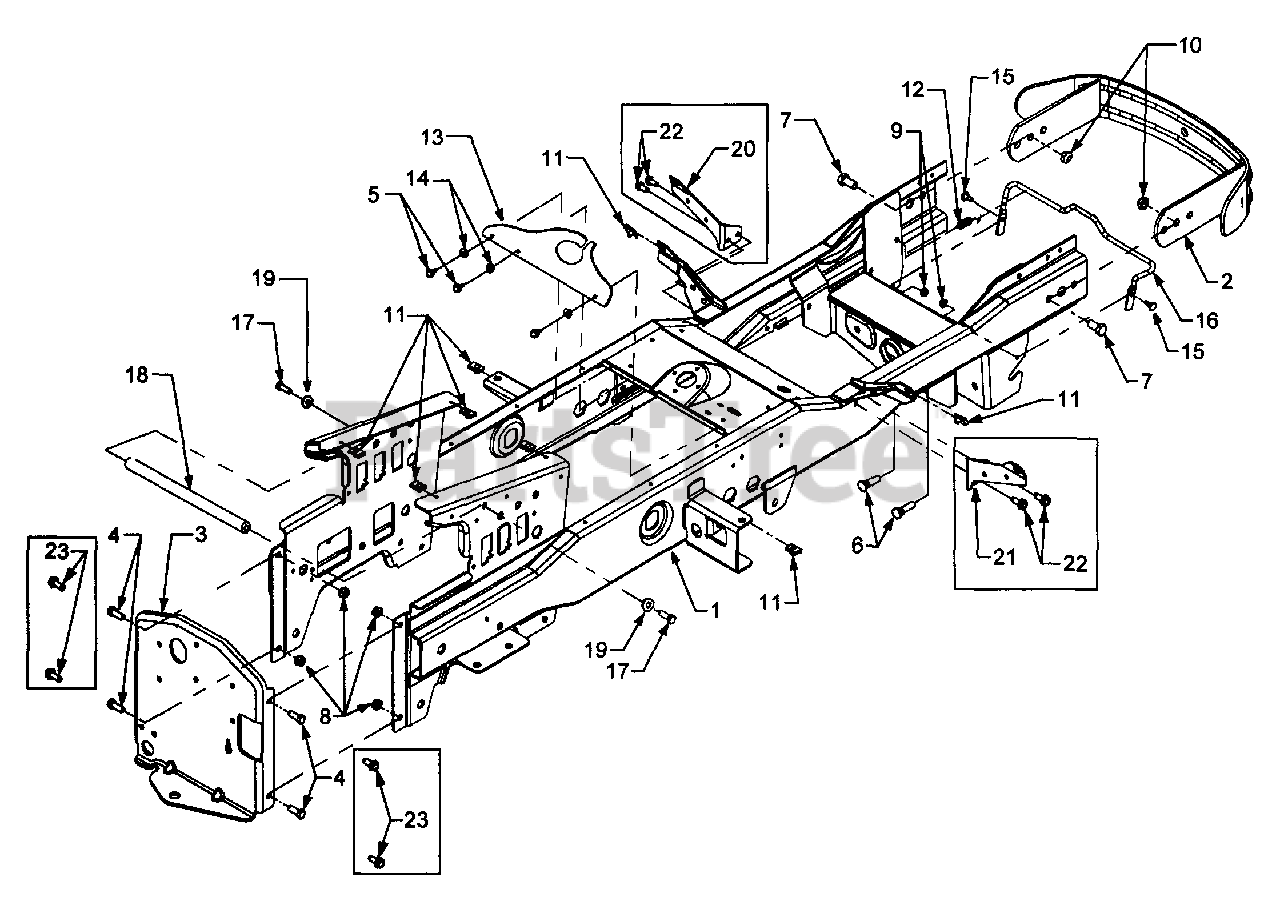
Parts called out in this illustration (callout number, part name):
1	Frame Assembly
2	Bumper, Front
4	Screw, Hex Cap 3/8-16 x 1.0 GR5
5	Screw, Hex Wash. Hd. Tapp 1/4-20 x .5
6	Screw, Round Hd., 3/8-24
7	Screw, Hex Cap 1/2-13 x 1.0 GR5
8	Nut, Hex Flange Lock, 3/8-16
9	Nut, Hex Flange Lock, 1/4-20
10	Nut, Hex Lock, 1/2-13
11	Speed Nut, U-Type, 5/16-18
12	Spring, Extension
13	Flap, Intk.
14	Washer, Flat, .283 x .75 x .030
15	Shoulder Screw, .312 x .18
16	Rod, Front Latch
17	Screw, Hex Cap, 5/16-18 x .875
18	Shaft, Frame Brace
19	Washer, Flat, .344 x .75 x .12
23	Screw, Hex Wash. Hd. Tapp 3/8-16 x .75
